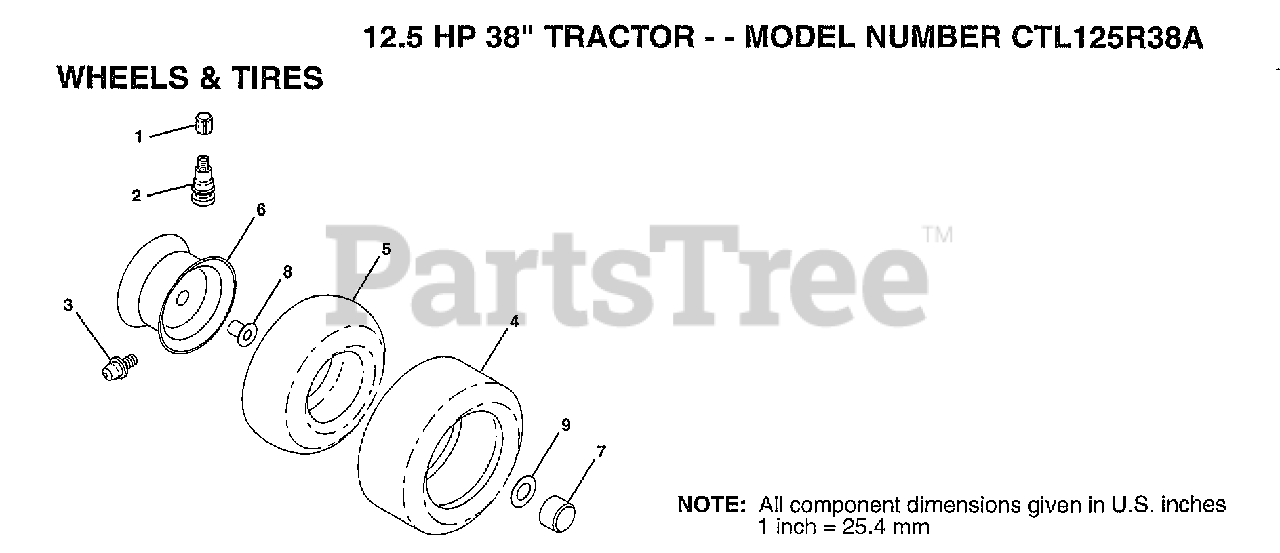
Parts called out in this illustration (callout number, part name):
1	VALVE CAP
2	VALVE STEM LT
3	FITTING LT
5	TUBE.5.3/4.5/6
5	TUBE.16X6.5/7.5-8
7	HUB CAP
8	"FLANGE, BEARING"
9	WASHER
